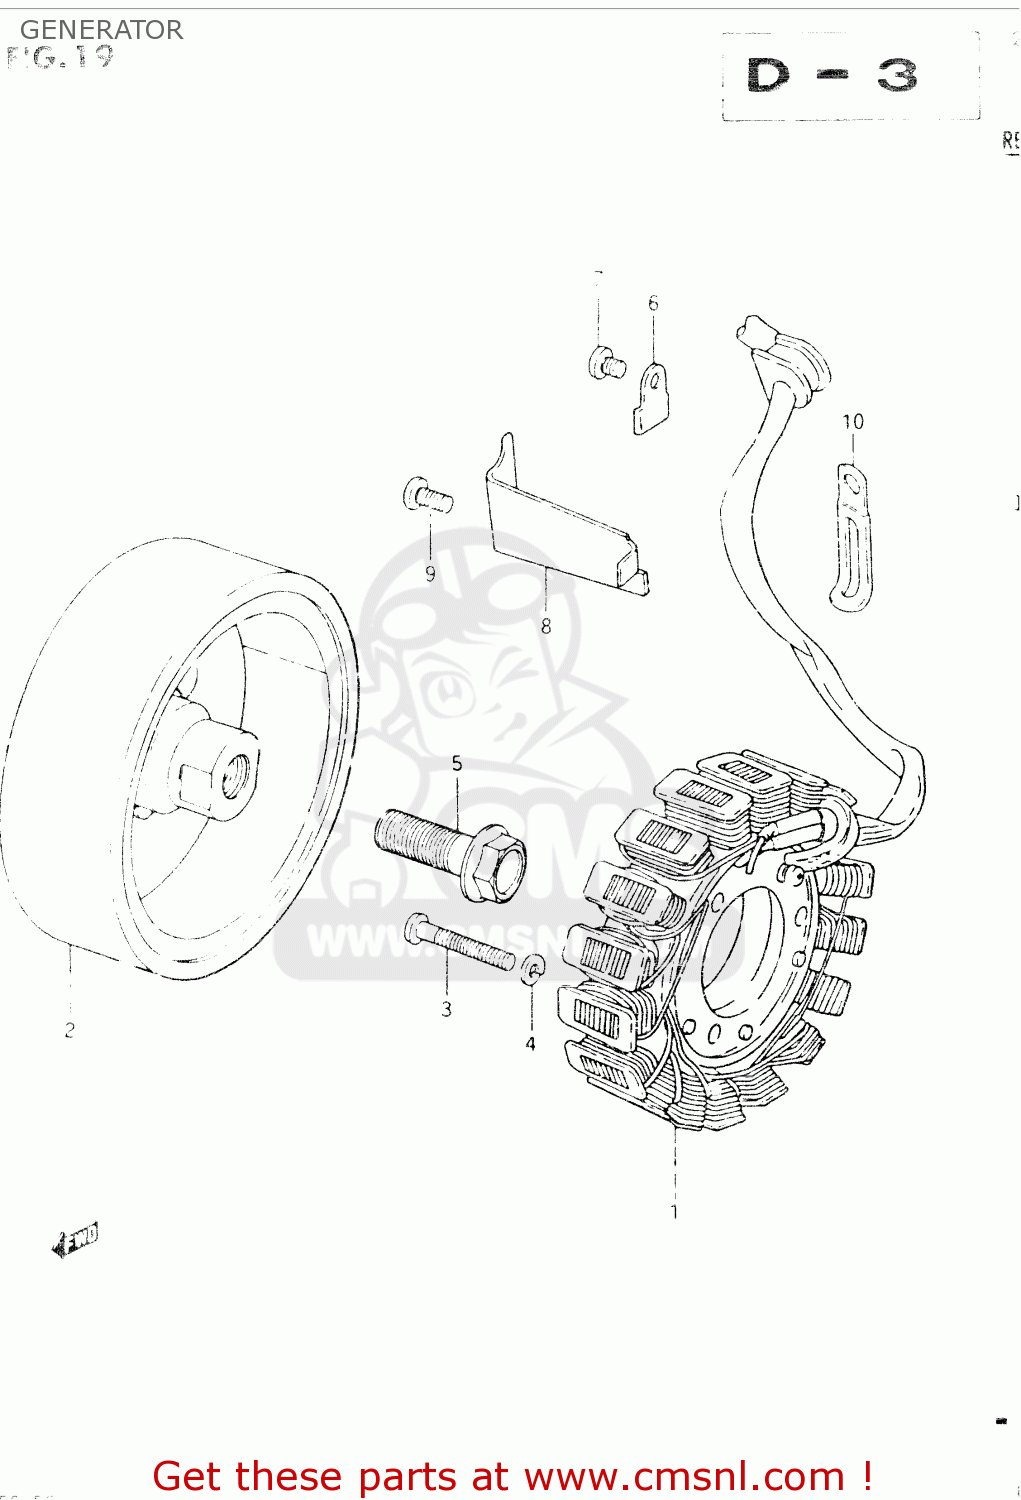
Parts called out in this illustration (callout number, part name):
1	STARTER ASSY
2	ROTOR ASSEMBLY
3	SCREW
4	LOCK WASHER
5	BOLT(12X40)
6	CLAMP,GENERATOR LEAD WIRE
7	SCREW
8	CLAMP,GENERATOR LEAD WIRE
9	SCREW
10	CLAMP L:35
